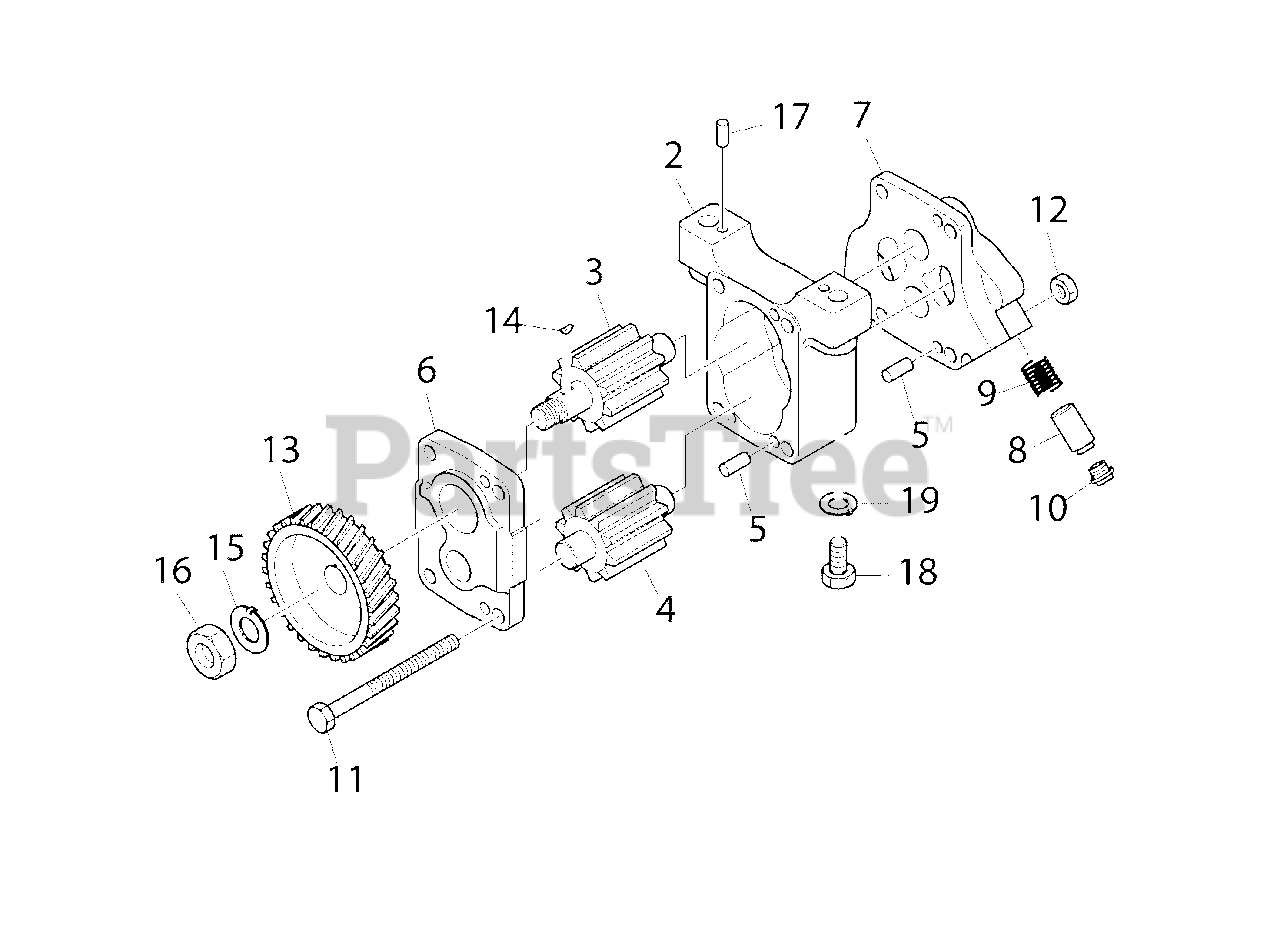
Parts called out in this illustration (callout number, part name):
1	* PUMP, OIL
2	* HOUSING
3	* GEAR, OIL PUMP
4	* GEAR, OIL PUMP
5	* PIN, DOWEL
6	* COVER, OIL PUMP
7	* COVER, OIL PUMP
8	* PLUNGER, VALVE
9	* SPRING, COMPRESS
10	* PLUG, SCREW
11	* BOLT
12	* NUT
13	* GEAR, OIL PUMP DRIVE
14	* KEY, WOODRUFF
15	* WASHER, LOCK
16	* NUT, HEX
17	* PIN, DOWEL
18	* BOLT, HEX
19	* WASHER, LOCK
